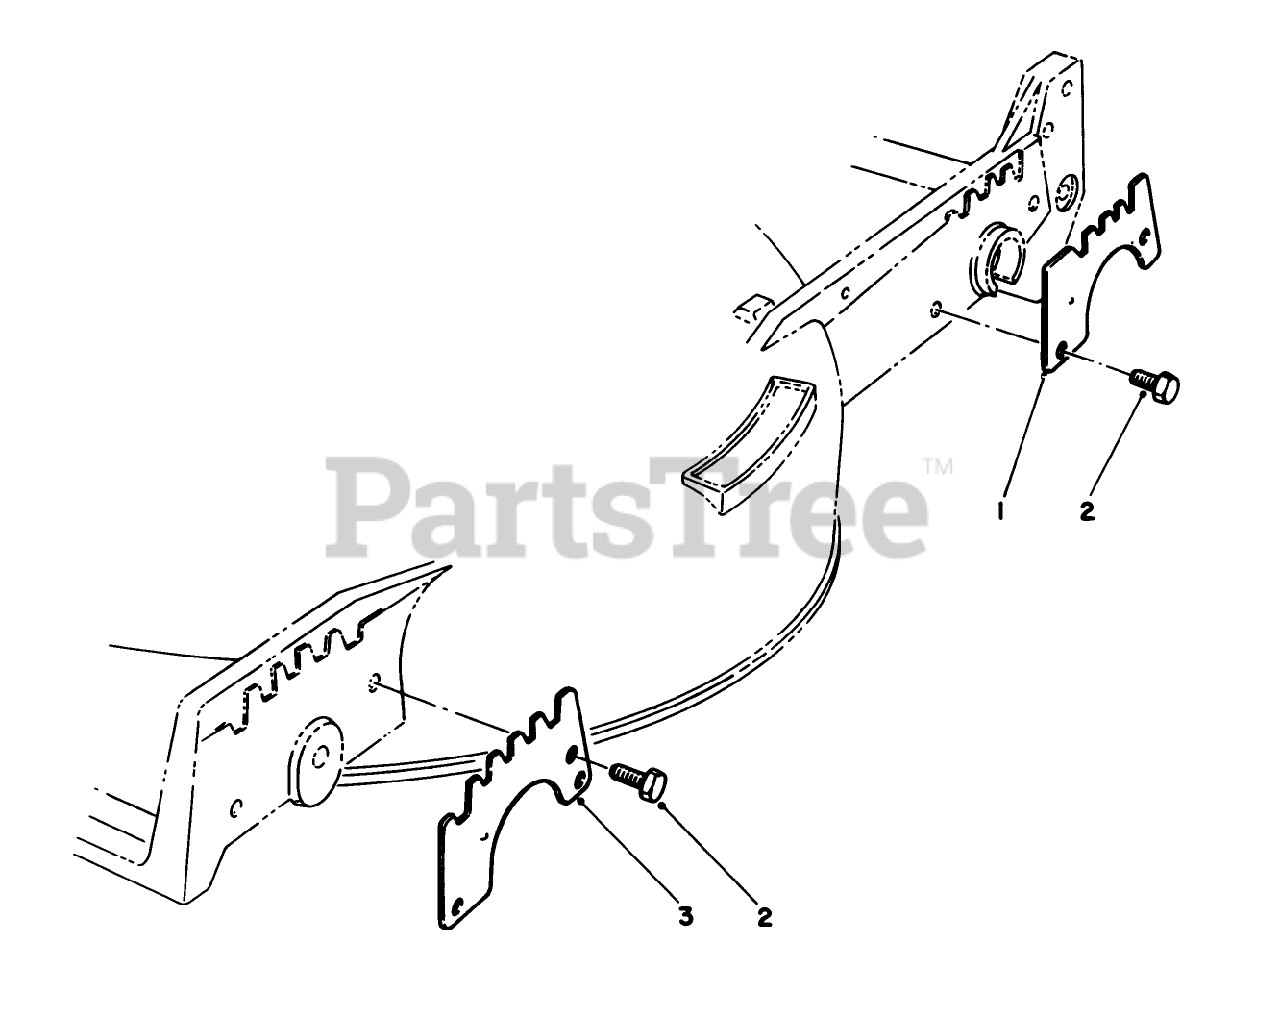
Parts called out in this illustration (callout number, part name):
1	WEAR PLATE,REAR
2	SCREW-HWH
3	WEAR PLATE
